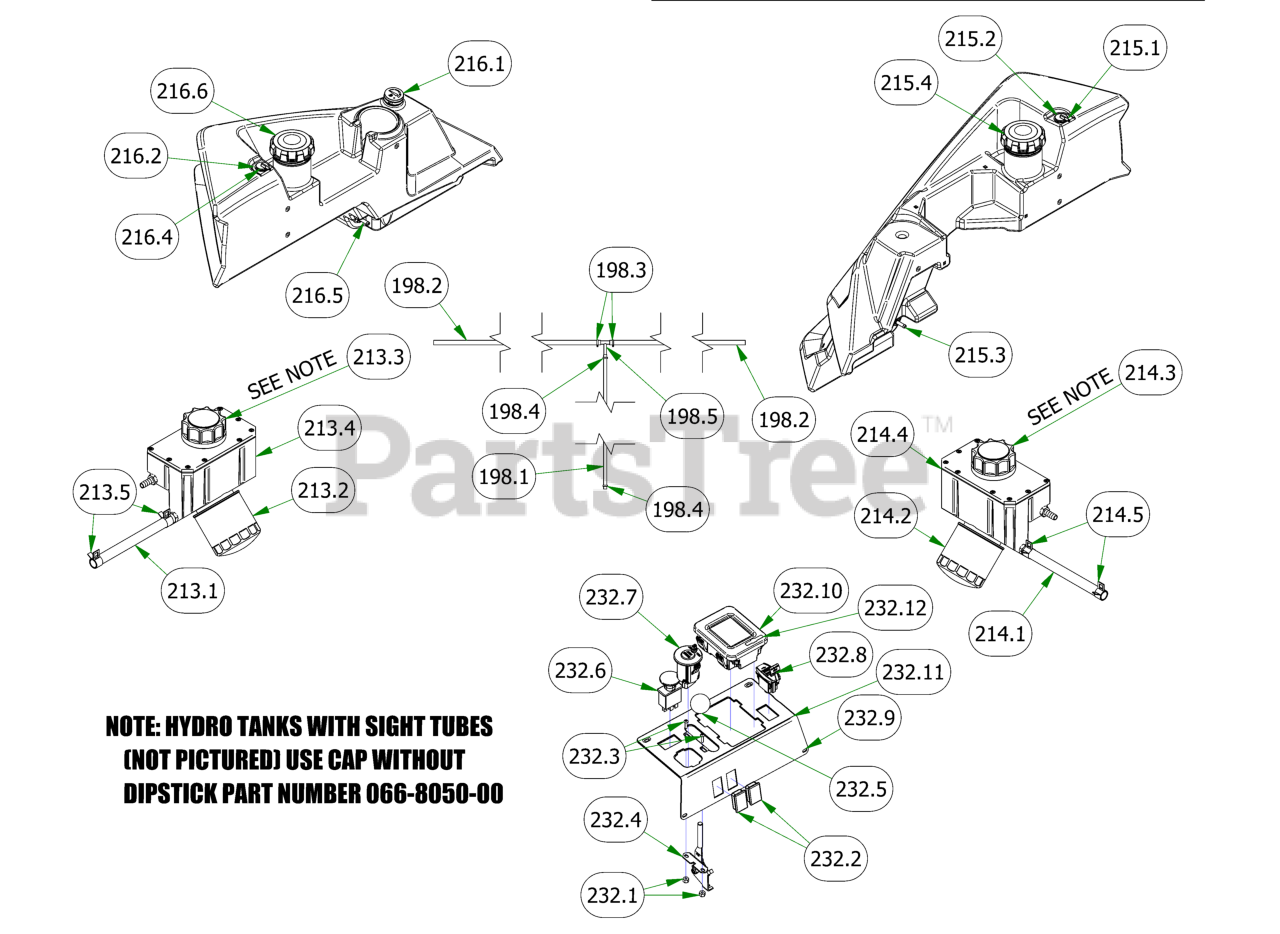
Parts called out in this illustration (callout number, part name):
198	2019 Rebel Rogue Renegade Fuel Line for Kohler
198.1	1/4" Fuel Line Hose
198.2	5/16" fuel line hose
198.3	5/16 Fuel Line Clamp
198.4	1/4 Fuel Hose Clamp
198.5	5/16 x 5/16 x 1/4 Fuel Line T
213	LH Rogue Hydro Tank Assy
213.1	1/2 Clear Braded Hose Priced/Foot
213.2	Hydraulic Filter
213.3	Hydraulic Tank Cap W/Dipstick
213.4	2019 Left Outlaw Gen2 Hydro Tank Suspension Only
213.5	1/2 Hose Clamp
214	RH Rogue Hydro Tank Assy
214.1	1/2 Clear Braded Hose Priced/Foot
214.2	Hydraulic Filter
214.3	Hydraulic Tank Cap W/Dipstick
214.4	2019 Right Outlaw Gen2 Hydro Tank Suspension Only
214.5	1/2 Hose Clamp
215	2019 Right Rebel, Rogue, Renagade Fuel Tank (GAS)
215.1	Roll Over Valve Grommet
215.2	Rollover Valve
215.3	Fuel Pick-up
216	2019 Left Rebel, Rogue, Renegade Fuel Tank (GAS)
216.1	Fuel Gauge with Grommet
216.2	Roll Over Valve Grommet
216.3	Fuel Gauge Grommet
216.4	Rollover Valve
216.5	Fuel Pick-up
232	Renegade Control Panel Assembly
232.1	10-24 Nylon Insert Locknut
232.2	Light Plug
232.3	10-24 X 5/8 BS Button Head Bolt
232.4	Universal Throttle Head - 2012
232.5	Throttle Knob
232.6	PTO Switch
232.7	2019 Push to Start Switch w/fob
232.9	2019 Outlaw Digital Control Panel
232.10	2019 LED Display
232.11	2022 Renegade (Gas) Control Panel Decal
232.12	2022 Digital Display Decal
